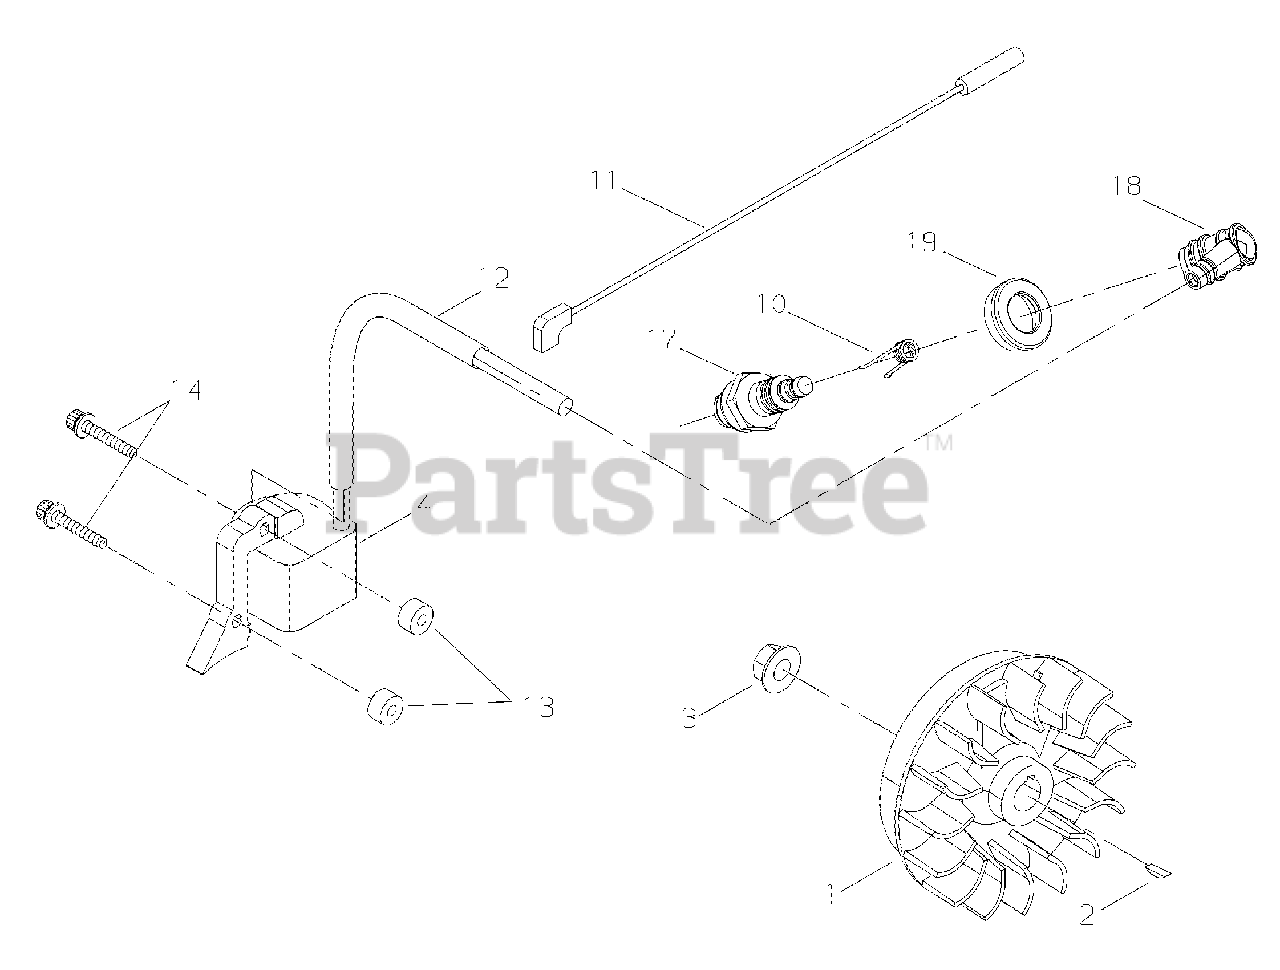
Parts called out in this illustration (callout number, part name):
1	FLYWHEEL
2	KEY - 3X10
3	NUT - 8
4	COIL, IGNITION
10	TERMINAL, SPARK PLUG CAP
11	LEAD - IGNITION
12	TUBE
13	INSULATOR
14	SCREW - 4X20
17	SPARK PLUG -- BPMR-6A
18	CAP, SPARK PLUG
19	SEAL, DUST
